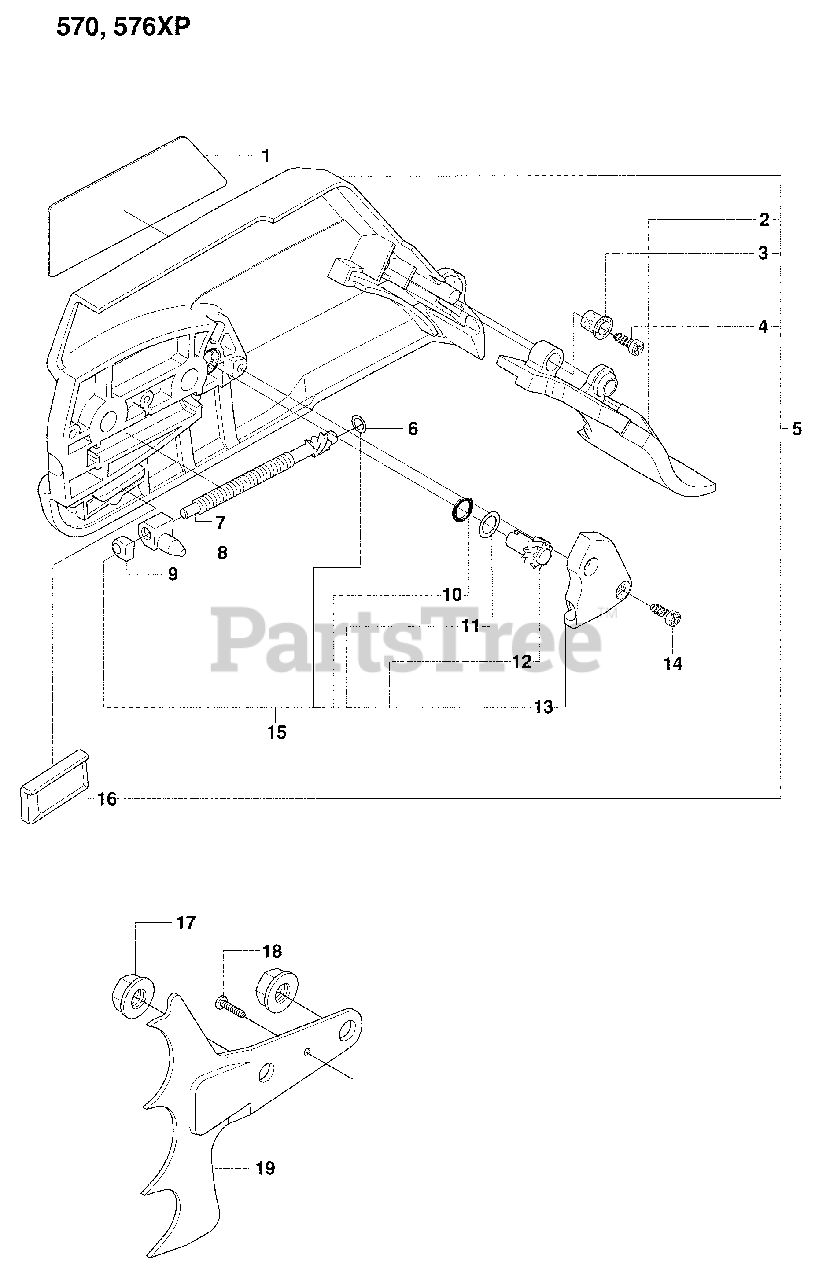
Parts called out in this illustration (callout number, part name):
5	Chain Brake Cover
5	Clutch Cover Assembly
7	Worm Screw with Adjuster
12	Worm Wheel
15	Chain Tensioner Kit
16	Chain Guide
17	Flange Hex Nut, M8
19	Felling Dog
